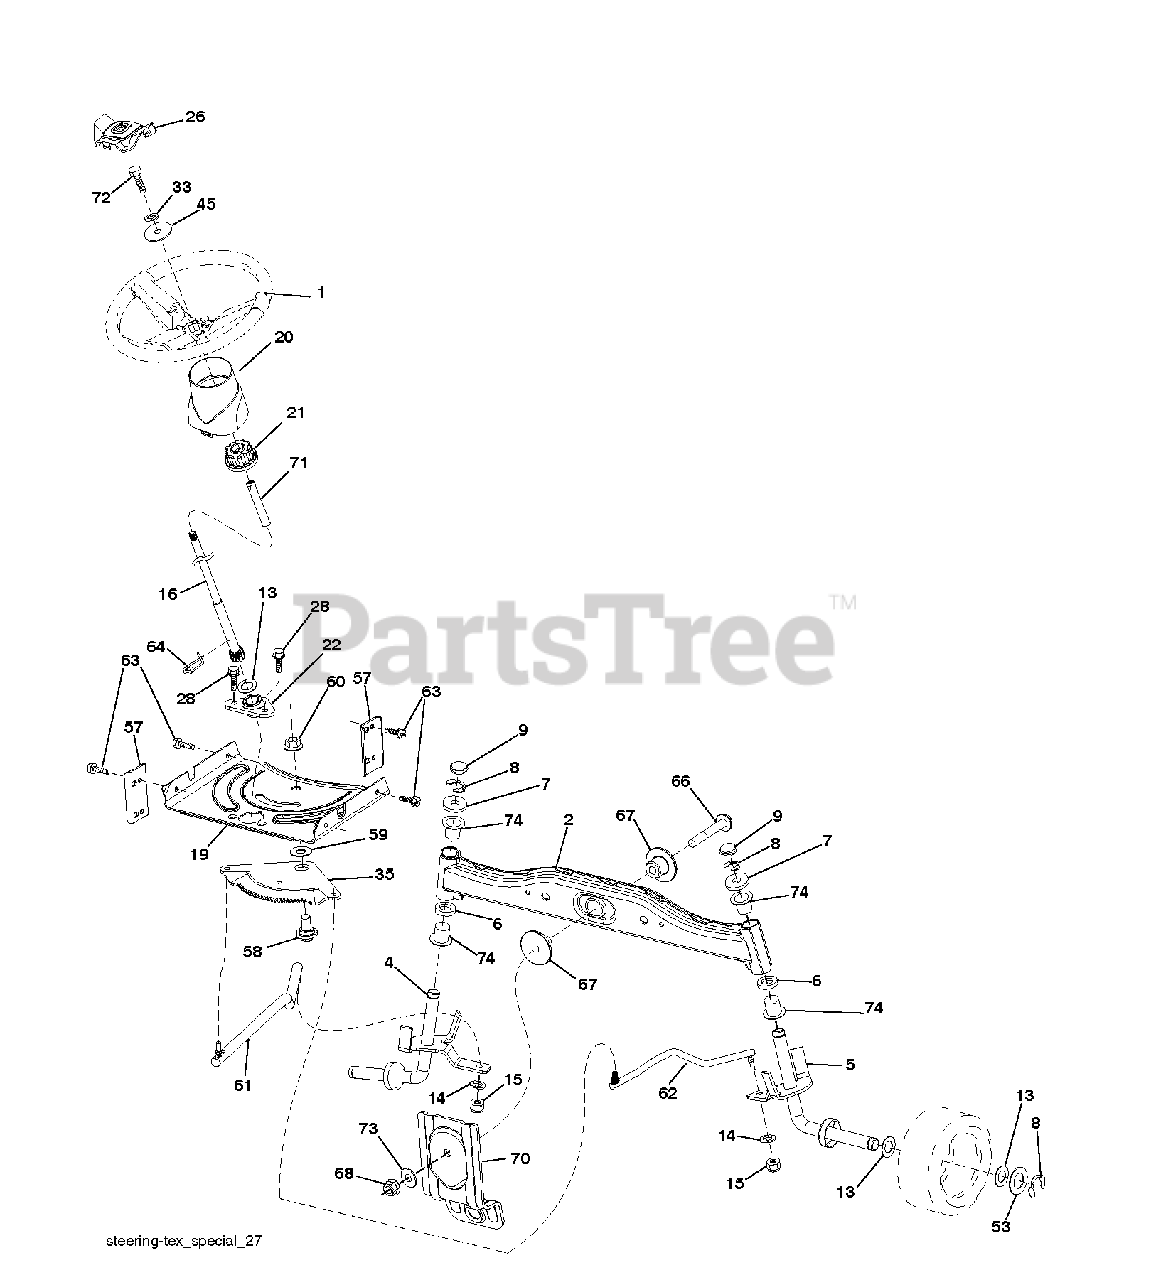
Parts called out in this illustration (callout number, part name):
1	WHEEL.STEERING.STDSRR.BLK/OV
2	AXLE HALF ASM-WELDED
4	SPINDLE.WELDED.LH.15"TEX
5	SPINDLE.WELDED.RH.15"T
8	RING CLIP
9	CAP.SPINDLE
14	WASHER, LOCK 3/8
15	NUT CROWNLOCK 3/8-24
16	SHAFT STEERING
19	PLATE.STEER.DDL.NLT/NG
20	BOOT.STEERING.PREDATOR.LT.BLAC
21	ADAPTER, WHEEL STNG..
22	BUSHING.ASM.STEERING.A
26	CAP.WHL.STRNG.STDSRRD.SRS.BLK
28	SCREW, 3/8-16X3/4
33	LOCKWASHER
35	GEAR.SECTOR.PLATE.DDL.
45	WASHER.11/32
53	WASHER.HARDENED
57	BRACKET.UPSTOP.TEX
58	BOLT.SHOULDER.SECTOR.P
59	WASHER.THURST.SECTOR.S
60	NUT FLANGE LOCK 5/8-11
61	DRAGLINK.LH.BALLSTUD.D
62	DRAGLINK.RH.BALLSTUD.D
63	SCREW
64	RETAINER.CLIP.SPRING.S
66	BOLT HEX FGHD 7/16-14 X 3 SERR
67	BUSHING.PM.FRONT AXLE
68	NUT.LOCK.FLANGE.7/16
70	BRKT.DECK.SUSPENSION.F
71	SHAFT EXTENSION STEERING
72	BOLT YT
73	WASHER.1.5X.505X.118
74	BRNG T
